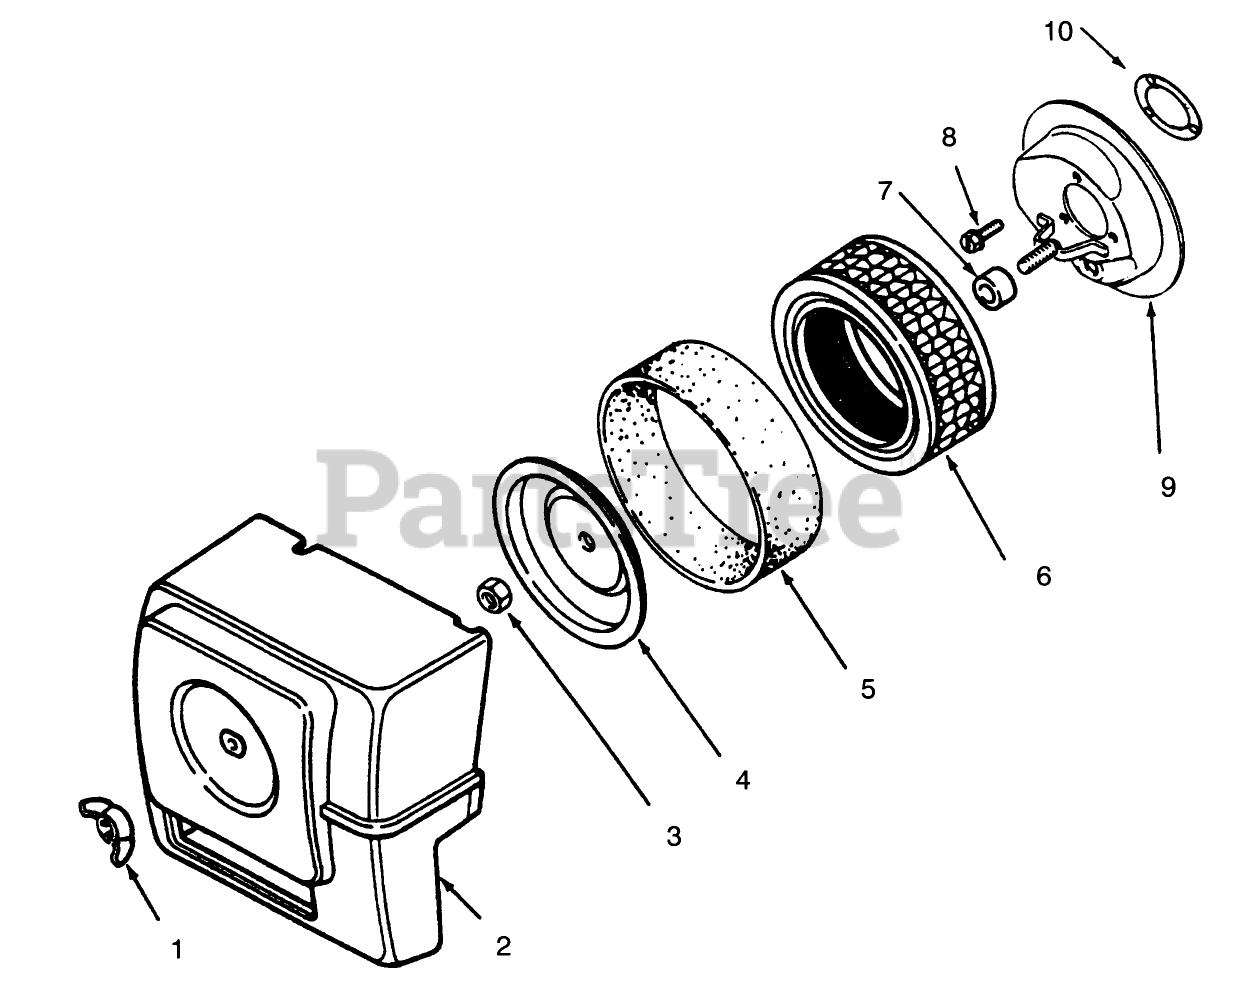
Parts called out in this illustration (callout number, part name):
1	KOHLER X-276-7
2	KOHLER 47-096-10
3	KOHLER 41-100-04
4	KOHLER 52-082-04
5	KOHLER45-083-01
6	KOHLER 45-083-02
7	KOHLER 231032
8	KOHLER X-67-65
9	KOHLER 47-094-20
10	KOHLER 45-041-07
